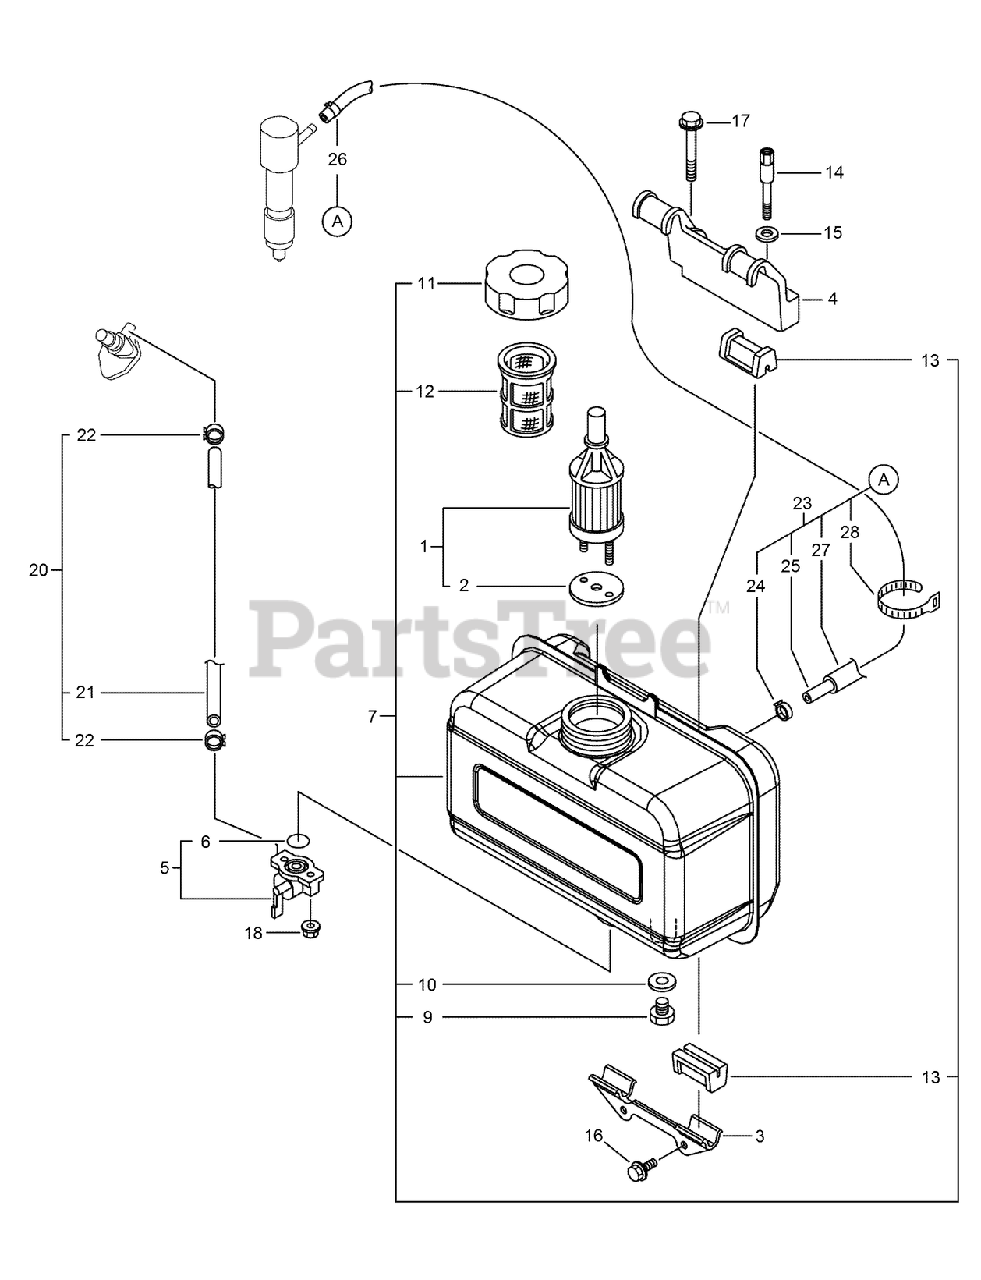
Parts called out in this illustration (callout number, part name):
1	FUEL FILTER ASM
2	GASKET
3	STAY A-TANK, FUEL
4	STAY B-TANK, FUEL
5	FUEL COCK ASM
6	O-RING
7	FUEL TANK ASM
9	PLUG-DRAIN
10	GASKET
11	FUEL TANK CAP ASM
12	FILTER-FUEL
13	DAMPER-TANK, FUEL
14	BOLT-LIFTING
15	WASHER
20	FUEL PIPE ASM
21	PIPE-FUEL
22	CLAMP-HOSE
23	RETURN PIPE ASM
24	CLAMP-HOSE
25	PIPE-RETURN, FUEL
26	CLAMP-HOSE
27	PROTECTOR-TUBE
